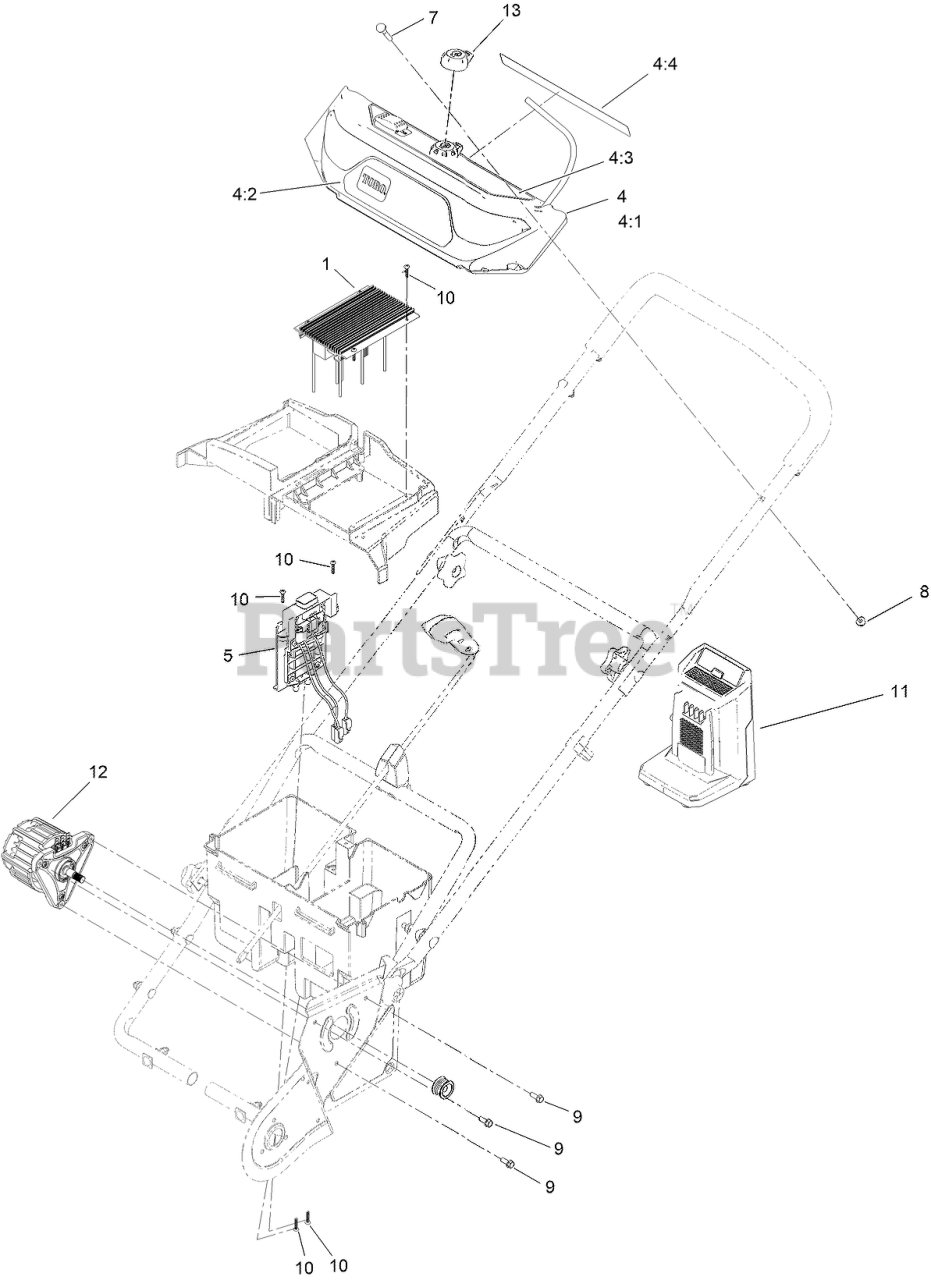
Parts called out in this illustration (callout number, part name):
1	MOTOR-DRIVER, SNOW (60V)
4	DASH PANEL ASM W/DECALS
4:1	DASH PANEL ASM
4:2	DECAL-POWER CLEAR
4:3	DECAL-OPERATION
4:4	DECAL-CAUTION
5	BATTERY TRACK ASM
5	BATTERY TRACK ASSEMBLY
7	SCREW-HANDLE
8	NUT-HF
8	NUT-FLANGE, NI
9	SCREW-HWH
10	SCREW-PPH
11	CHARGER-60V (2A)
11	60V CHARGER
12	MOTOR ASM
13	KEY-BAIL
